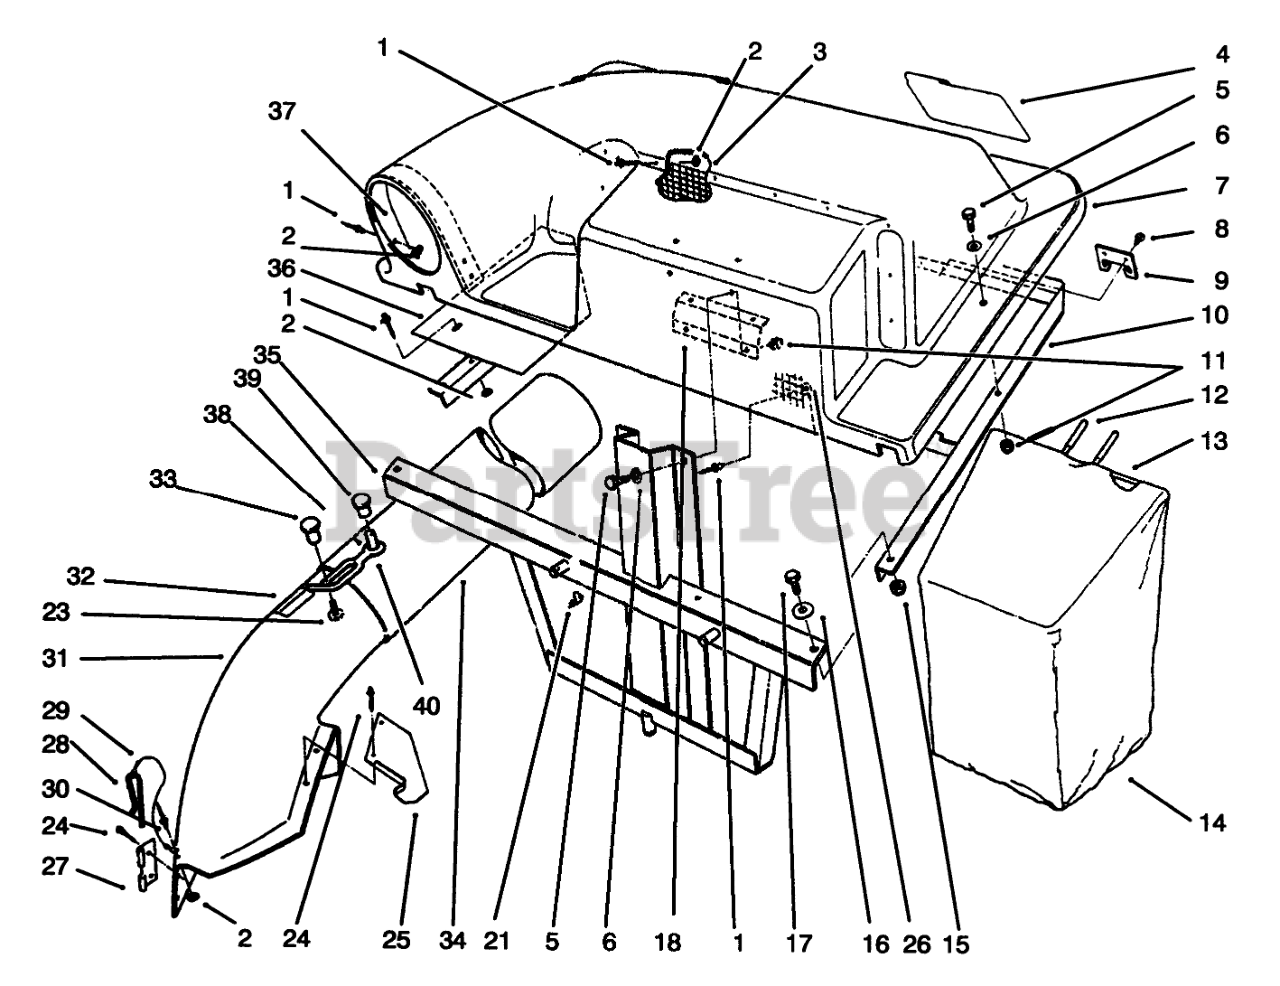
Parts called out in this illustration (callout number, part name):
1	RIVET-POP
2	WASHER-PLAIN
3	SCREEN
4	DECAL-BAGGER, TWIN
5	SCREW-HH
6	WASHER-PLAIN
7	COVER-BAGGER, TWIN
8	SCREW-HWH
9	BRACKET-FRAME, BAG
10	Cover-Frame
11	NUT-LOCK, NI
12	GRIP-HANDLE, BAG
13	Frame-Bag
15	NUT-LOCK, NI
16	WASHER-FLAT
17	SCREW-HH
18	Plate-Backup
21	PIN-HAIR
23	SCREW-HWH
24	RIVET-BLIND
25	CHUTE SUPT BRKT
27	BRACKET-MOUNTING, CHUTE
28	PIN-LOCKING, CHUTE
29	LANYARD
30	RIVET-BLIND
31	Assembly-Chute (Incl. Ref. #23-30 & 32-33)
32	DECAL-DANGER
34	GRASS DISCHARGE TUBE
35	Frame-Mounting
36	Baffle
37	Support Inlet
38	SPACER-INTERLOCK
39	FASTENER-PANEL
40	RETAINER-DUCT
